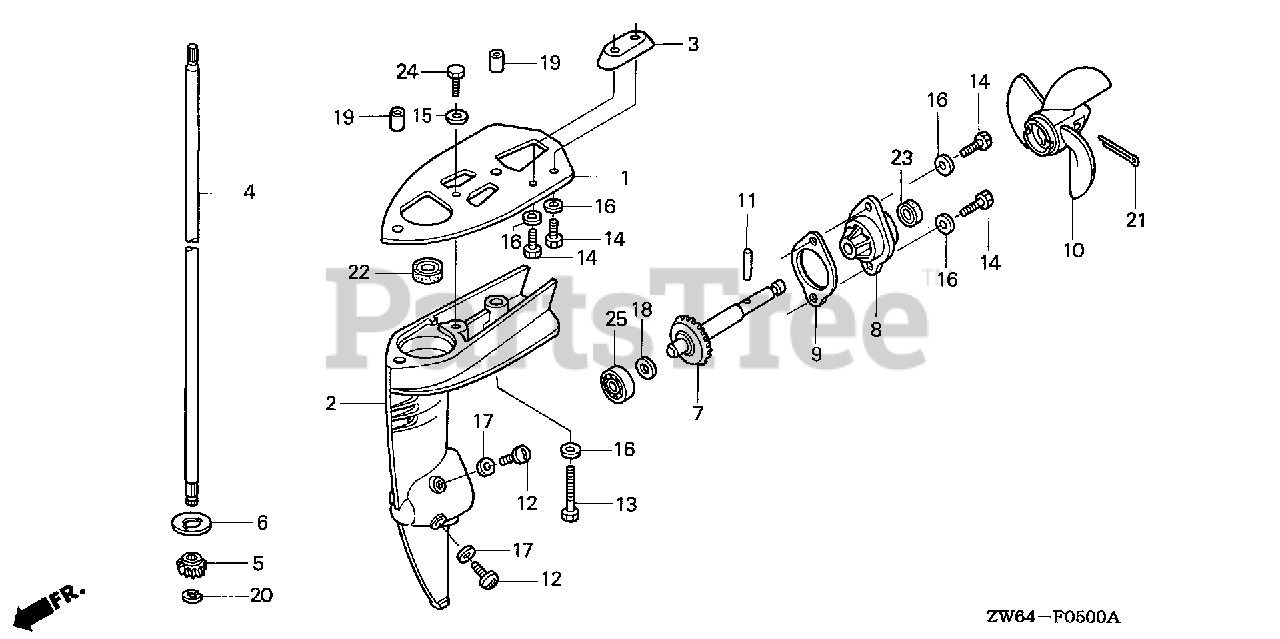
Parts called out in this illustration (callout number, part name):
2	CASE, GEAR *NH246* (LOOSY GRAY)
4	SHAFT, VERTICAL (S)
5	GEAR, PINION
6	WASHER, PINION THRUST
7	SHAFT, PROPELLER
8	HOLDER ASSY., PROPELLER SHAFT *NH246* (LOOSY GRAY)
9	GASKET, PROPELLER SHAFT HOLDER
10	PROPELLER, THREE-BLADE *NH283* (STIN GRAY)
11	PIN, SHEAR
12	BOLT, OIL CHECK
12	BOLT, OIL CHECK (8X8)
13	BOLT, HEX. (6X35)
14	BOLT, HEX. (6X16)
16	WASHER, PLAIN (6MM)
17	WASHER, NYLON (8MM)
18	WASHER, GEAR (1.00) (A)
18	WASHER, GEAR (1.05) (B)
18	WASHER, GEAR (1.10) (C)
18	WASHER, GEAR (1.15) (D)
18	WASHER, GEAR (1.20) (E)
19	PIN, DOWEL (8X14)
20	E-RING (6MM)
21	PIN, SPLIT (3MM)
21	PIN, SPLIT (3.0)
22	SEAL, WATER (11X21X8)
23	SEAL, WATER (11X21X8)
25	BEARING, RADIAL BALL (6000)
